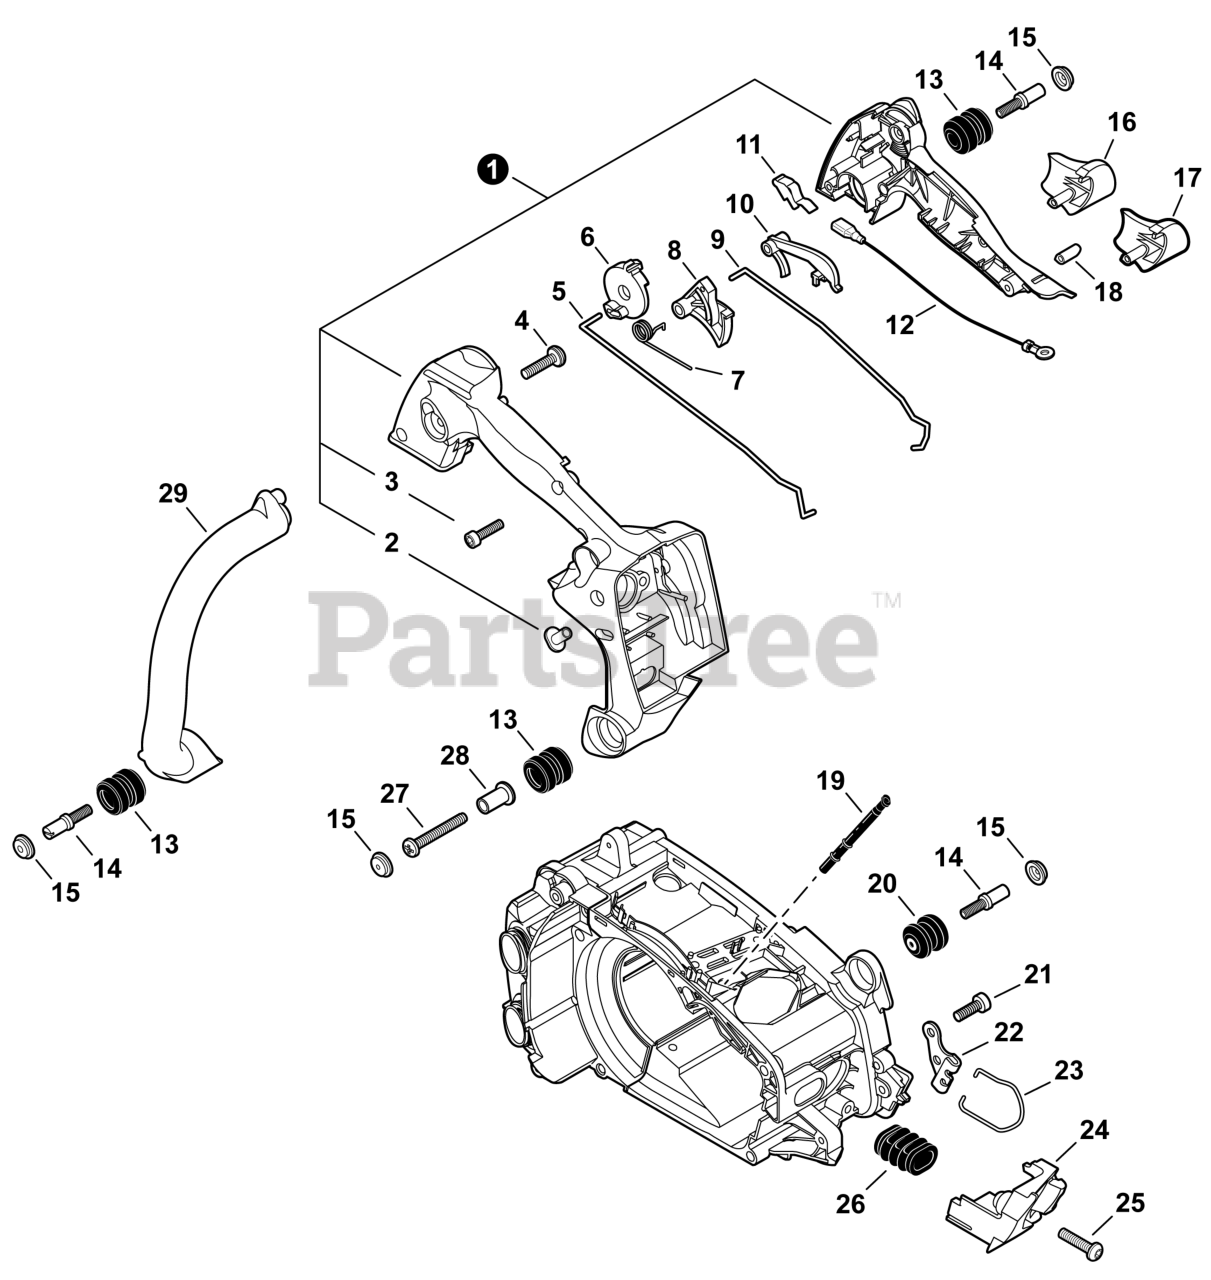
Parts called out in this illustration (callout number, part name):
1	HANDLE SET, REAR
3	BOLT, TORX 4x16
4	BOLT, TORX 5x20
5	ROD, CHOKE
6	LEVER, CONTROL
7	SPRING, TORSION
8	TRIGGER, THROTTLE
9	ROD, THROTTLE
10	LOCKOUT, THROTTLE
11	TERMINAL, GROUND
12	LEAD - GROUND
13	CUSHION 4
14	BOLT 4x12
15	CAP, CUSHION
16	SUPPORT, HANDLE - LARGE
17	SUPPORT, HANDLE - SMALL
19	PIPE, PULSE 3x7x80
20	CUSHION 4
21	BOLT, TORX 5x12
22	BRACKET, STRAP
23	RING, HARNESS
25	BOLT, TORX 5x20
26	BELLOWS, INTAKE
27	SCREW, TAPPING 4x35
28	COLLAR 4
29	HANDLE, FRONT
